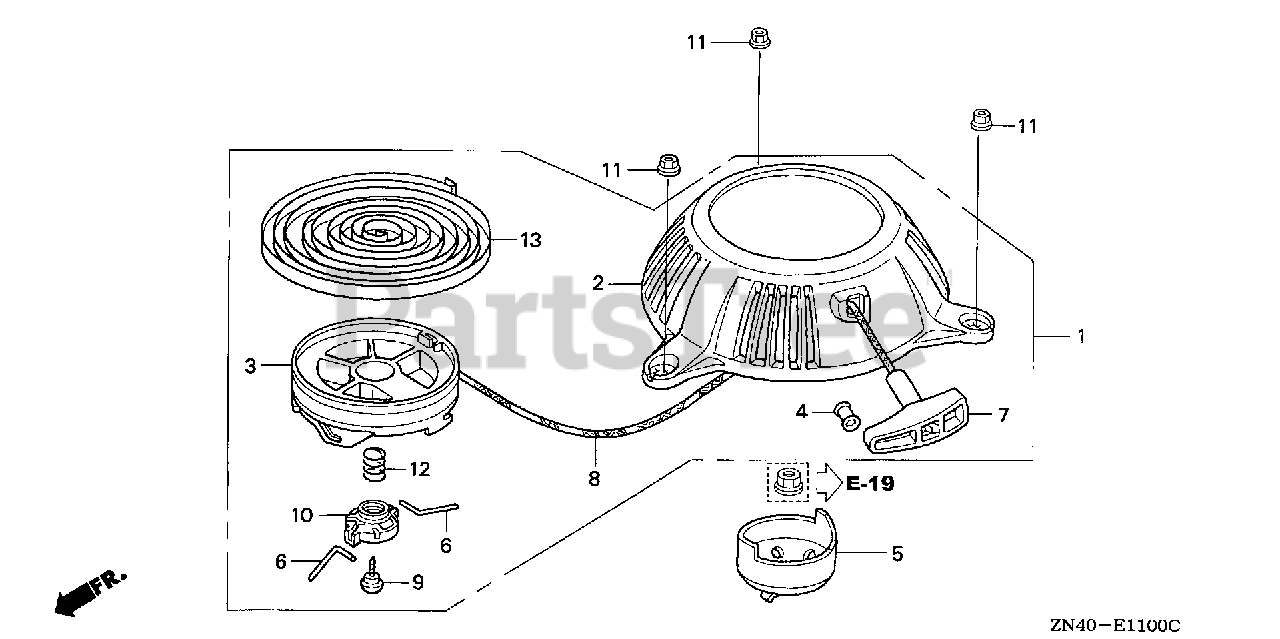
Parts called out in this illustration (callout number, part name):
1	STARTER ASSY., RECOIL
2	CASE, RECOIL STARTER
3	REEL, RECOIL STARTER
4	GUIDE, ROPE
5	PULLEY, RECOIL STARTER
7	KNOB, RECOIL STARTER
8	ROPE, RECOIL STARTER
9	SCREW, SETTING
11	NUT, FLANGE (5MM)
12	SPRING, FRICTION
13	SPRING, RECOIL STARTER
